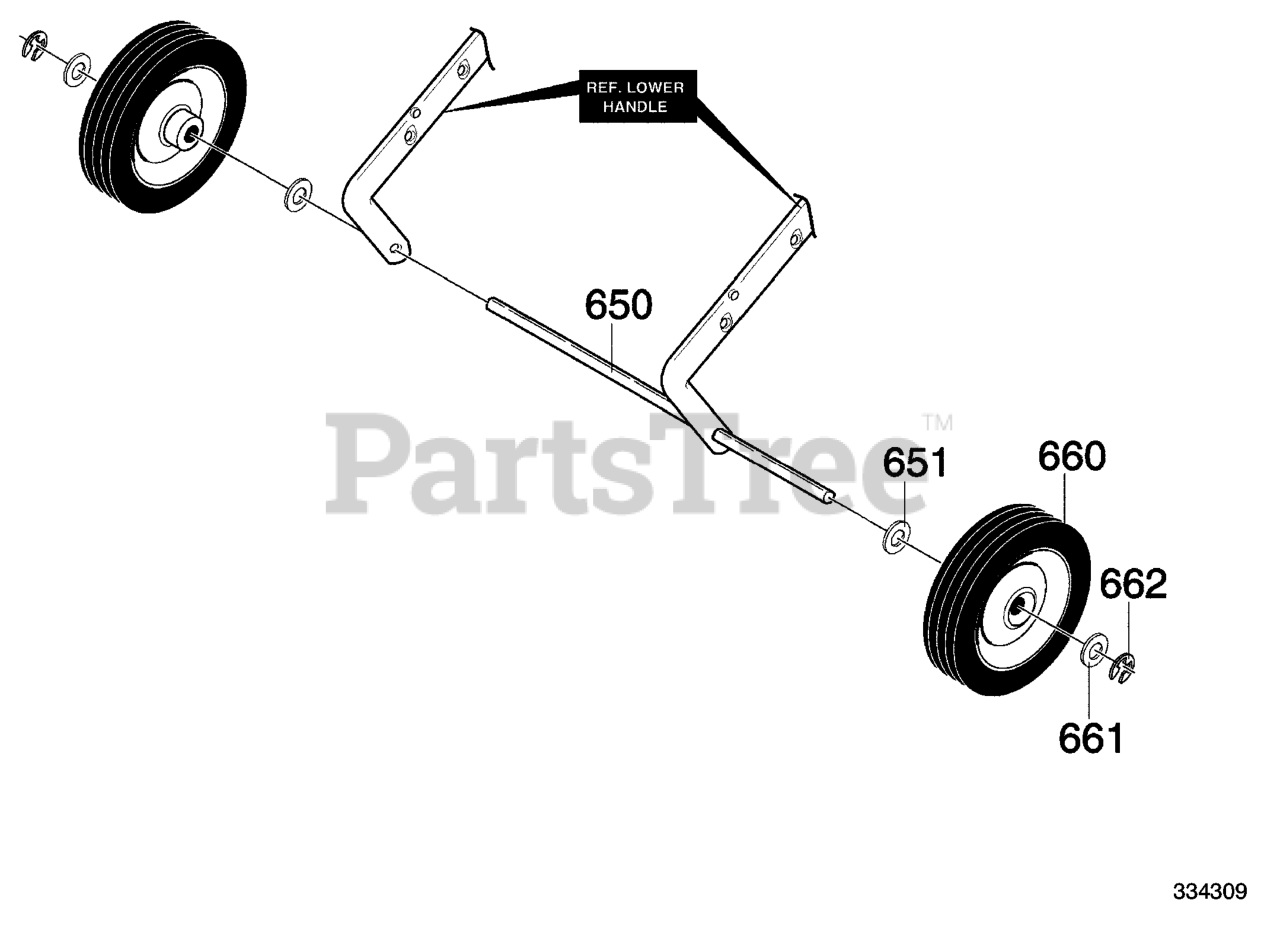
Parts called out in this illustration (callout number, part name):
650	AXLE SHAFT
651	WASHER, FLAT .391X1.00X1.25
660	TIRE & RIM
661	WASHER, FLAT .391X1.00X.125
662	RING, RET E
